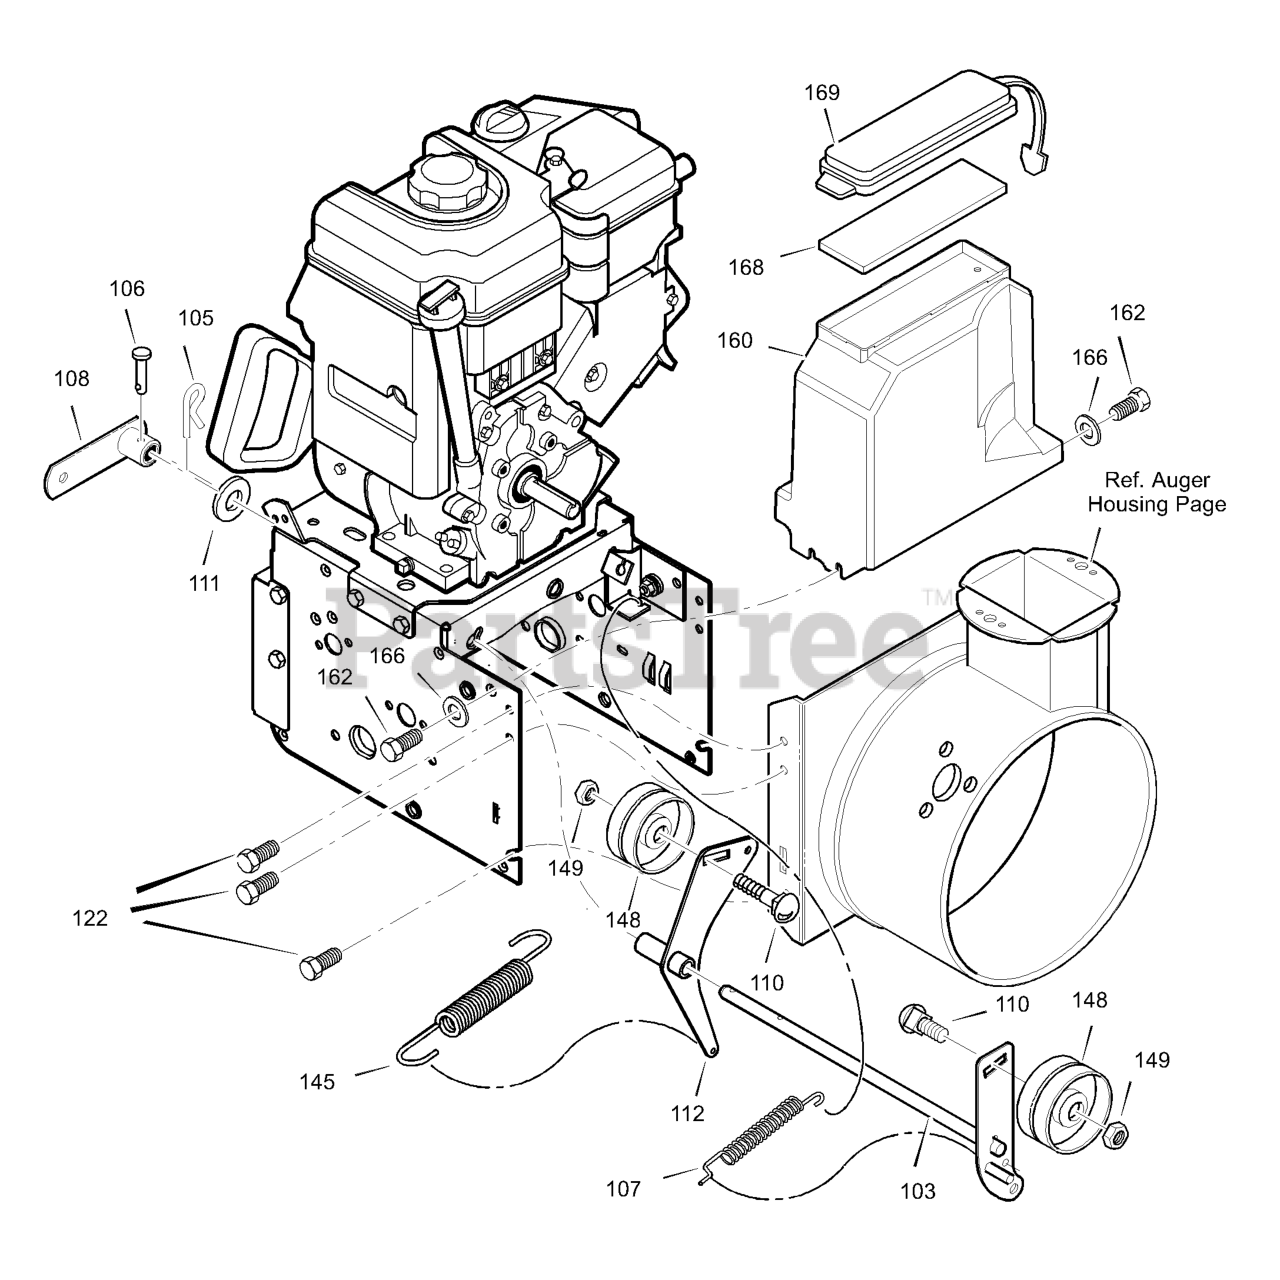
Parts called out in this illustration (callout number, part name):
103	ASSY, AUGER IDLER
105	PIN, HAIR
106	PIN, CLEVIS 3/16" DIA
107	SPRING, TENSION
108	SPRING ATTACHMENT
110	BOLT, 3/8-16X1.25
111	WASHER, FLAT
112	BRACKET, IDLER
122	SCREW, 5/16-18 x 0.50
145	SPRING, CLUTCH
148	PULLEY, IDLER
149	NUT, JAM 3/8-16
160	COVER, BELT
162	SCREW, 1/4-20 X .63
166	WASHER, FLAT
168	PAD, FOAM
